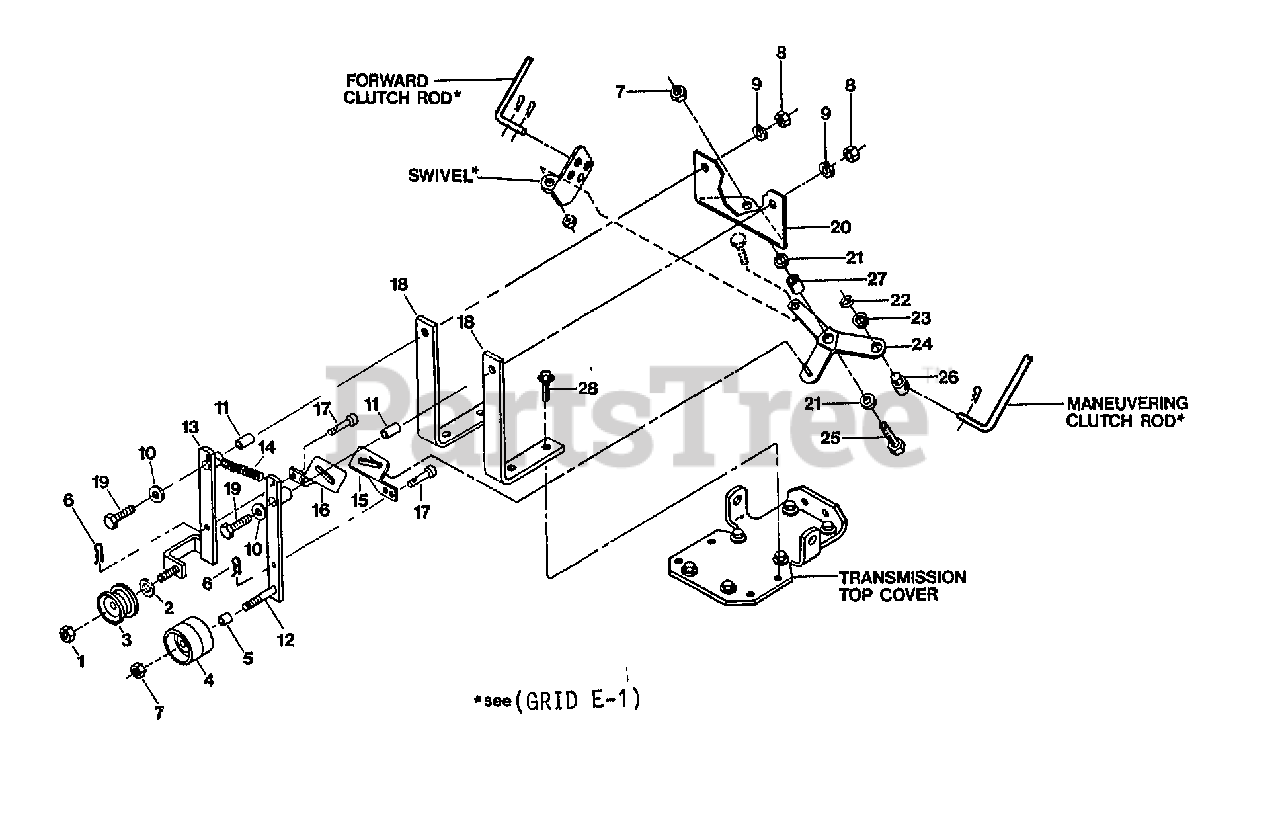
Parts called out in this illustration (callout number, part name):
1	NUT-LOCK 3/8-16 NYLON ZP
2	BUSHING-.54X.38X.08
3	IDLER-REV
3	PULLEY-IDLER REVERSE
4	PULLEY-FWD IDLER
5	BUSHING-.5X.375X.3
6	PIN-CLIP .08
7	NUT-H/LK 3/8-16
8	NUT-HEX 5/16-18 ZP
9	WASHER-LK .312 ZP
10	WASHER-#.75X.32X.09 ZP
11	BUSHING-.438X.323X.712
12	ARM-IDLER FWD PNT
13	IDLER-REV
13	ARM-IDLER REV RED
14	SPRING-.436 X 3.25
15	LINK-FWD
17	PIN-CLEVIS .375X.719 ZP
18	MOUNT BAR-PNT (20691)
19	SCR-HH 5/16-18X2.25 G5ZP
20	SHIFT BASE-OPC PNT
21	SPACER-.88X.385X.09 ZP
22	RING-KLIP .500 ZINC
23	WASHER-#.88X.51X.063 ZP
24	BELLCRANK-OPC PNT
25	SCR-HH 3/8-16X1.25
26	PIVOT-ROD
27	BUSHING-.5X.38X.4
28	SCR-HFLK 5/16-18X1.00 ZP
